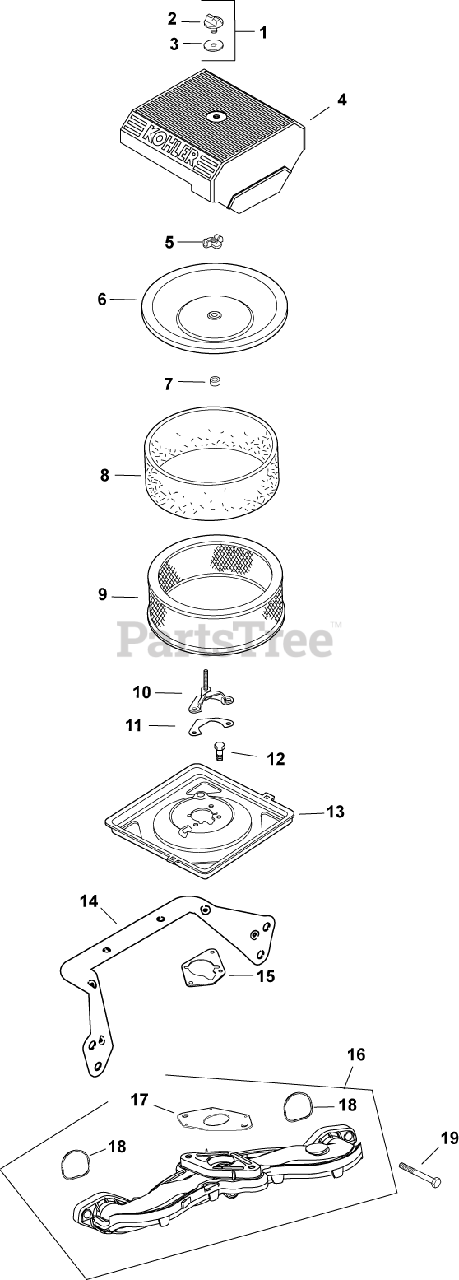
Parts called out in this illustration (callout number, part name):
1	KIT, KNOB W/SEAL
2	KNOB, COVER
4	COVER, AIR CLEANER
5	NUT, WING
6	COVER, INNER AIR CLEANER
7	SEAL, BREATHER
8	PRE-CLEANER (HIGH)
9	ELEMENT, AIR FILTER (HIGH) - Also available Retail Packaged 24 883 03-S1 Air Filter Kit
10	CUP, FUEL SPITBACK W/O NIPPLE
11	GASKET, FUEL SPITBACK CUP
12	SCREW, FLG THD FRM M5X.8X10
13	BASE, AIR CLEANER-USE 24 094 82-S
14	BRACKET, AIR CLEANER BASE
15	GASKET, AIR CLEANER BASE
16	MANIFOLD, INTAKE - PLASTIC-USE 24 164 91
17	GASKET, CARBURETOR
18	O-RING, INTAKE PORT
19	SCREW, FLG M6X1.0X40
